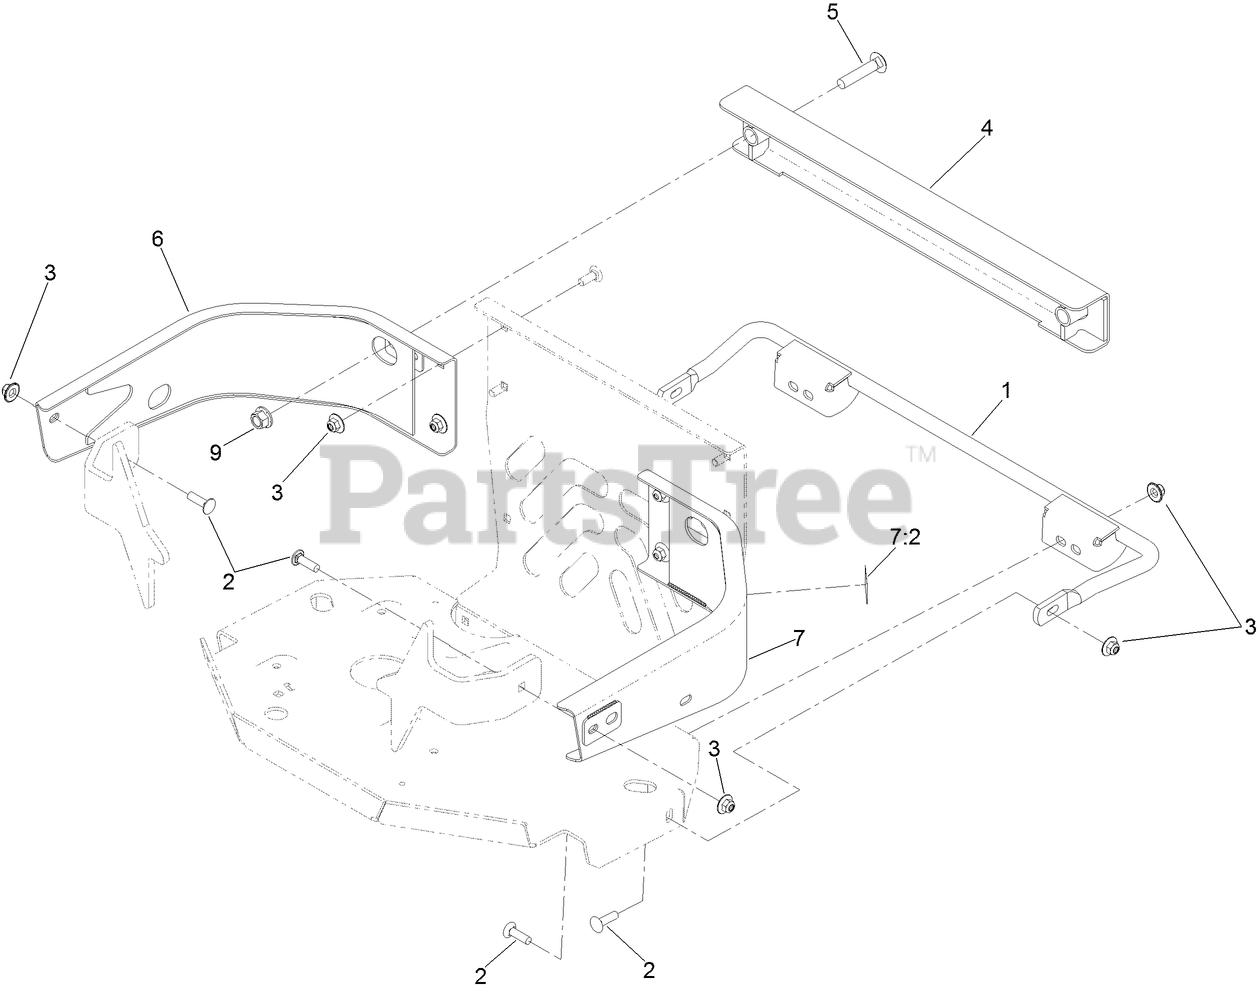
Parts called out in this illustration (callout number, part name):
1	MOUNT-BAGGER, LOWER
2	SCREW-CARR
3	NUT-FLANGE, NI
4	MOUNT-BAGGER, UPPER
5	SCREW-CARR
6	BUMPER-RH
7	LH BUMPER ASM
7:2	DECAL-WARNING
9	NUT-LOCK
